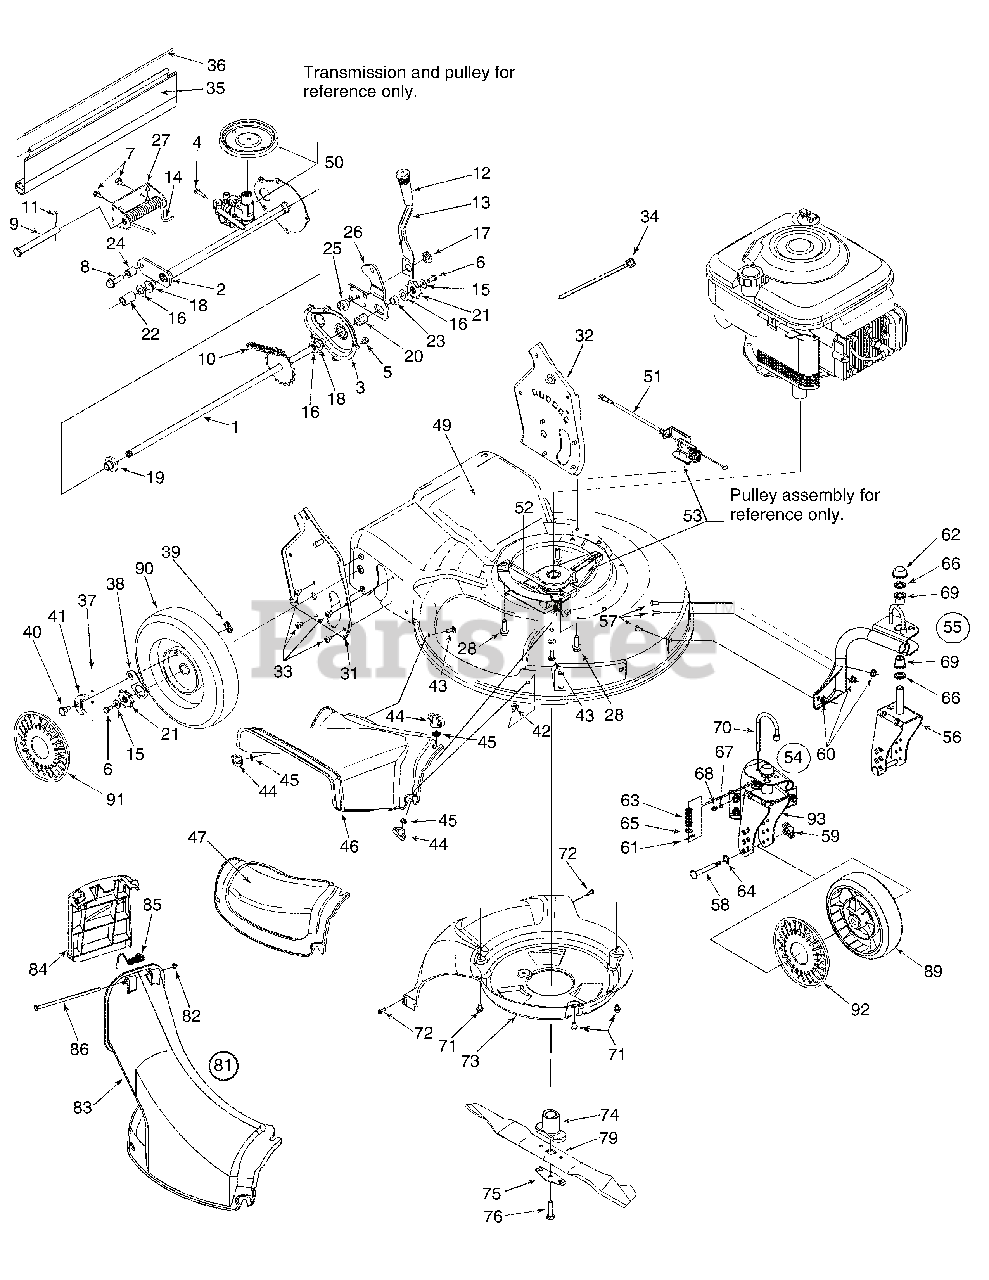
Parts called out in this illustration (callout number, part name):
1	Axle Ass’y 20T x 21.46" Lg.
5	Hex Wash HD Tapp Scr 1/4-20 x .38
6	Hex Bolt 1/4-20 x .62
7	Hex Wash Hd. Scr 1/4-20 x .625" Lg
8	TT Screw 3/8-16 x 1.25
9	Clevis Pin .5" Dia. x 4.62" Lg.
10	Chain, No. 48 Endless .50 x 24 links
14	RH Torsion Spring
15	Cupped Wash. .25 ID x .88 OD x .062
16	Washer, Flat .505 ID x 1.0
17	Shoulder Nut .625 DIA. x .165
18	Flange Bearing .506 ID
19	Hex Flange Bearing
20	Hex Sleeve Bearing .504 x .830 Lg.
21	Ratchet Wheel
22	Spacer .55 ID x .75
23	Sleeve .511 ID x .70 OD x .37" LG.
24	Spacer .38 x .625" Lg.
25	Shoulder Spacer .385 ID x .715" Lg.
35	Rear Flap 17.25" Lg.
36	Rear Flap Wire
37	Spring Nylon
38	Pawl Plate
39	Toplock Flat Weldnut 1/4-20
40	Shoulder Screw .340 x .285: 1/4-20
42	Carriage Bolt 1/4-20 x .62
43	Carriage Bolt 1/4-10 x .75
44	Wing Nut
45	Bolt Retainer 1/4" x .50" OD
47	Mulching Baffle
51	SP Cable 51.0" Lg.
52	V-Belt 3/8 x 39.24" Lg.
57	Carriage Bolt 5/16 x 18 x .62" Lg.
58	Caster Axle
59	Wing Nut
60	Hex Flange L-Nut 5/16-18 Gr. F
61	Int. Cotter Pin 5/16 DIA
62	Push Cap 5/8" Dia Rod
63	Com pression Spring
64	Spring Washer .530 ID
65	Flat Washer .344 ID x .625 OD x .063
66	Flat Washer .63 ID x .12 OD x .12
67	Flat Washer .203 ID x .406 OD x .040
68	Grease Fitting
69	Flange Bearing .631 ID
71	Hex Wash HD Tapp Scr 1/4-20 x .38
72	Screw 1/4-15 X .75
73	Baffle
74	Blade Adapter
75	Bell Blade Support
76	Hex Bolt 3/8-24 x 2.00 Gr. 8 Special
79	Blade 21"
81	Chute Assembly
82	Push Cap .188 Rod
83	Top Chute
84	Chute Door
85	Torsion Spring
89	Front Wheel Ass’y 7 x 2
89	Front Wheel Ass'y 8 x 2.125
90	Rear Wheel Ass’y 9 x 2.00
90	Rear Wheel Ass’y 9 x 2.125
91	Hub Cap -Grey
91	Hub Cap - Beige
91	Hub Cap -Yellow
92	Hub Cap -Grey
92	Hub Cap - Beige
92	Hub Cap -Yellow
